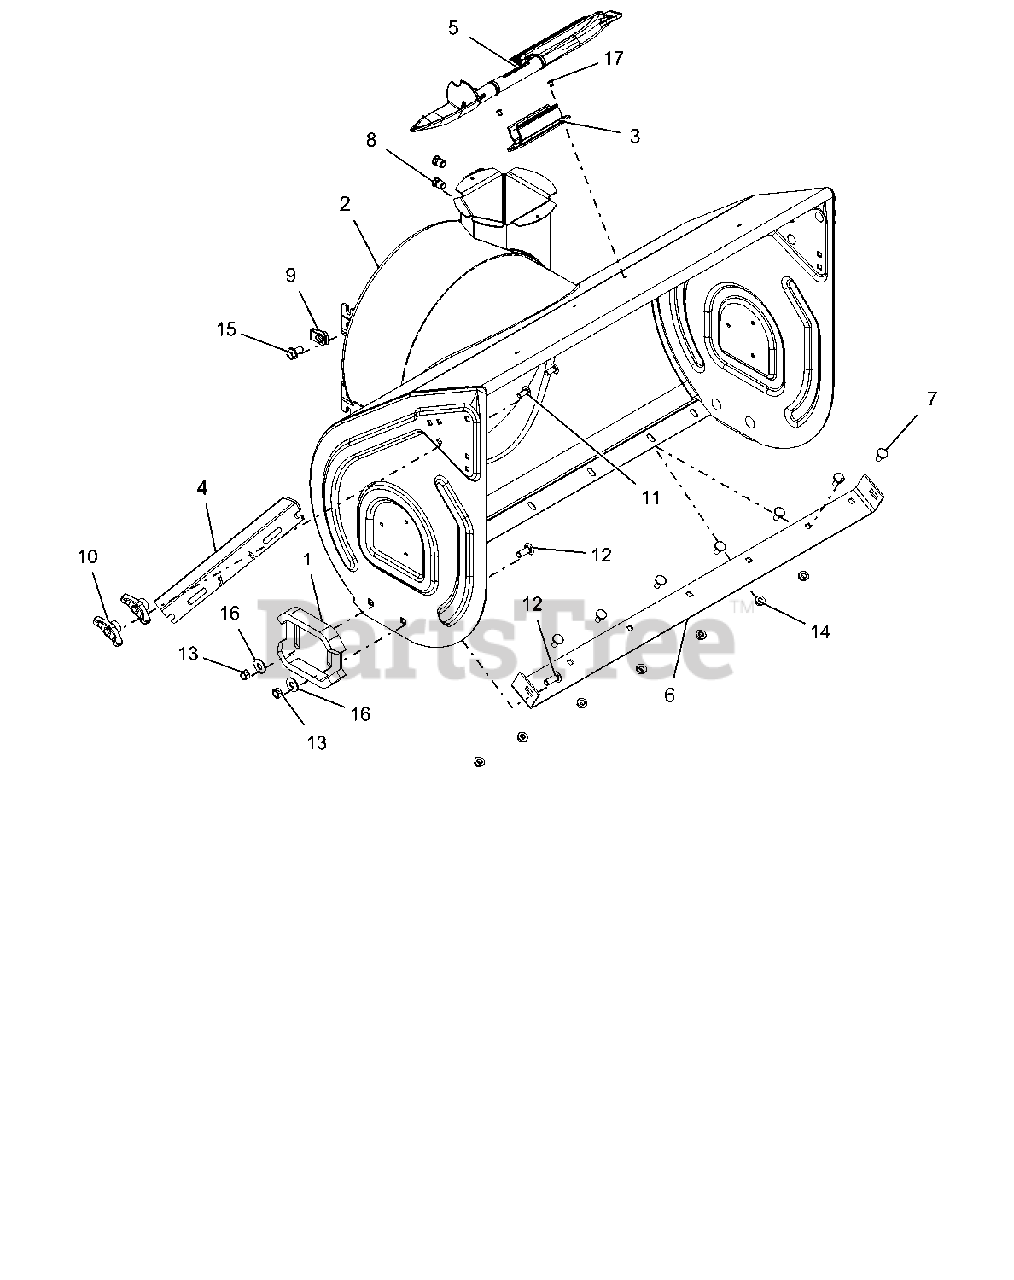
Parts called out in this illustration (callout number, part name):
1	RUNNER, SKID SHOE
2	BLOWER HOUSING W/DECAL 32"
3	MOUNT, SNOW CLEAN OUT
4	CUTTER, DRIFT
5	DEVICE, SNOW CLEAN OUT W/BRUSH
6	BLADE, SCRAPER-32"
7	BOLT, MODIFIED HEAD CARRIAGE
8	NUT, THREADED INSERT .38-16
9	NUT-RTNR .375-16X.37
10	KNOB,WING .31-18 UNC NYL/TALC
11	@BLT-RHDSSQNK .31-18X.75 G5YZ
12	@BLT-RDHDSHSQNK.38-16X1.0 G5YZ
13	@NUT-LK-CTR .38-16 YWZC
14	@NUT-LK-TOP-FLG .31-18 YWZC
15	BLT-SERHFWH .38-16X.75 YWZC
16	@WSHR-FL-STL.438X1.00X.083 YWZ
17	RVT-POP .187 YZ
